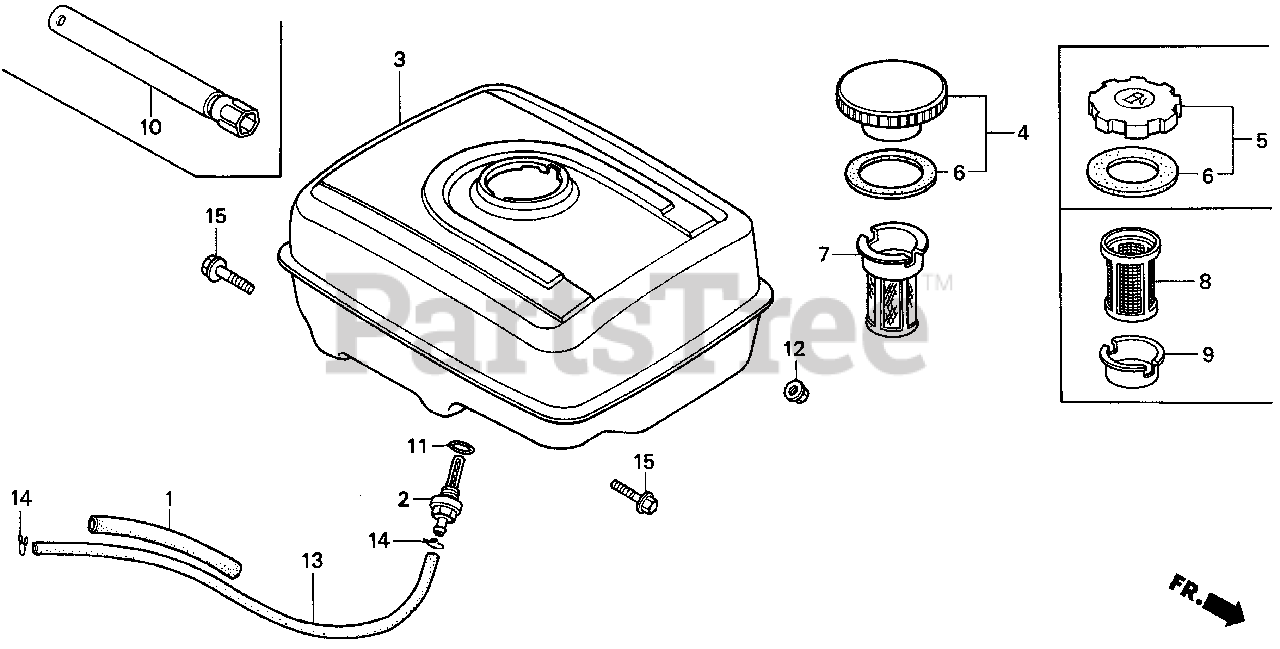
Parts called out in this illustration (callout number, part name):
1	RUBBER, SUPPORTER
1	RUBBER, SUPPORTER (107MM)
2	JOINT, FUEL TANK
3	TANK, FUEL *NH31* (MCKINLEY WHITE)
3	TANK, FUEL *NH1* (BLACK)
4	CAP, FUEL FILLER
5	CAP, FUEL FILLER
6	GASKET, FUEL FILLER CAP
7	FILTER, FUEL
8	FILTER, FUEL
9	HOLDER, FUEL FILTER
10	WRENCH, SPARK PLUG
11	O-RING (13.5X1.5) (ARAI)
12	NUT, FLANGE (8MM)
13	BULK HOSE, FUEL (4.5X3000) (4.5X222)
14	CLIP, TUBE (B8)
15	BOLT, FLANGE (8X25)
